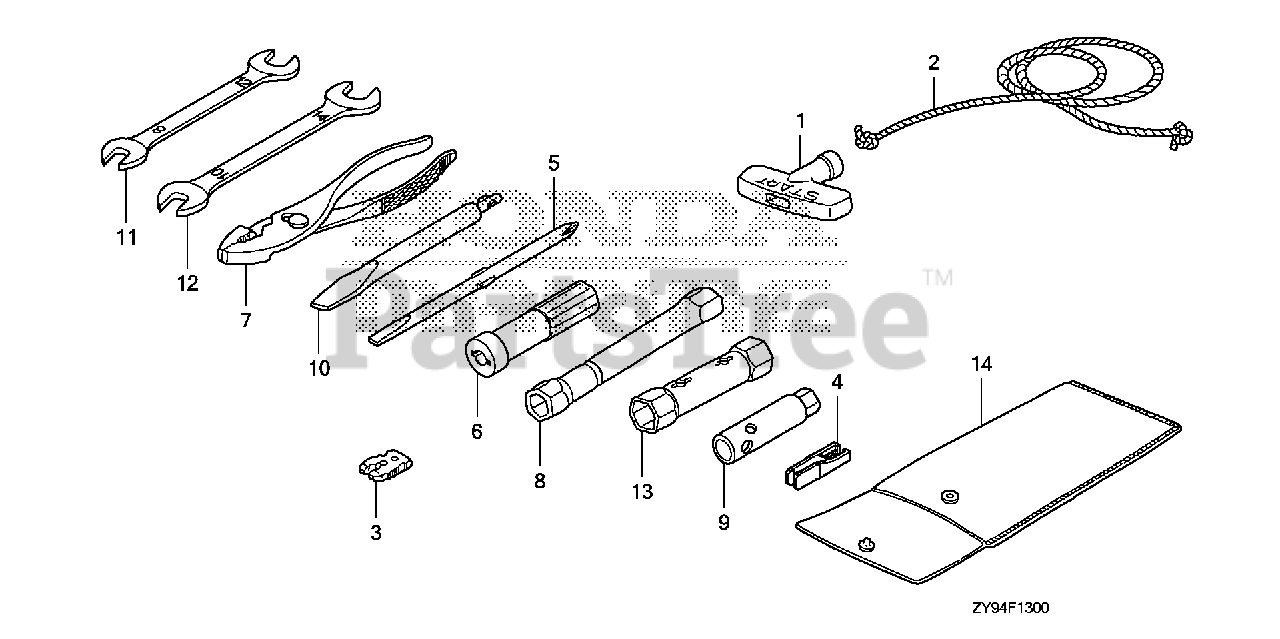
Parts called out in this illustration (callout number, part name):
1	GRIP, STARTER
1	KNOB, RECOIL SRARTER
2	ROPE, RECOIL STARTER (1300MM)
3	CLIP, EMERGENCY LOCK
4	PULLER, MINI FUSE (SUMITOMO)
5	SCREWDRIVER (NO.2 PHILLIPS -)
7	PLIERS (135) (RIKEN)
8	WRENCH, PLUG
9	WRENCH, BOX (10MM)
10	SCREWDRIVER, CHECK BOLT
11	SPANNER (8X12)
12	SPANNER (10X14)
13	WRENCH, BOX (P18X19)
